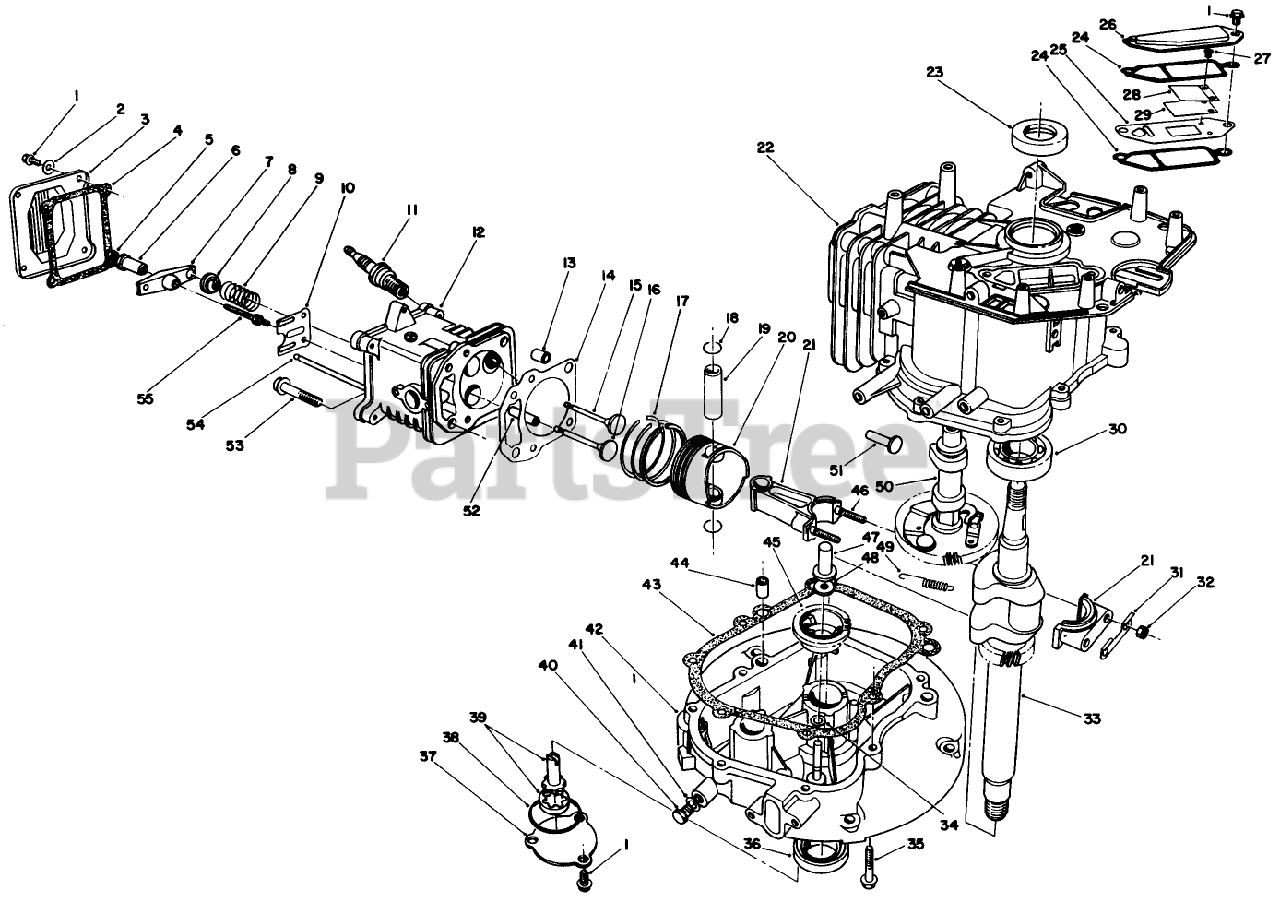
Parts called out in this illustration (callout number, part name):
2	WASHER
3	COVER
6	PIVOT
8	RETAINER
10	GUIDE
11	SPARK PLUG
12	CYLINDER HEAD
14	GASKET
16	VALVE-INTAKE
17	RING SET
22	ENGINE BLOCK
25	Plate-Breather
27	Screw-Reed Valve
28	Retainer-Reed Valve
29	Valve-Reed
30	BEARING
33	CRANKSHAFT
37	COVER
38	O-RING
40	OIL DRAIN PLUG
41	GASKET
43	GASKET
47	PLUNGER
48	WASHER
50	CAMSHAFT
51	TAPPET
52	GUIDE
